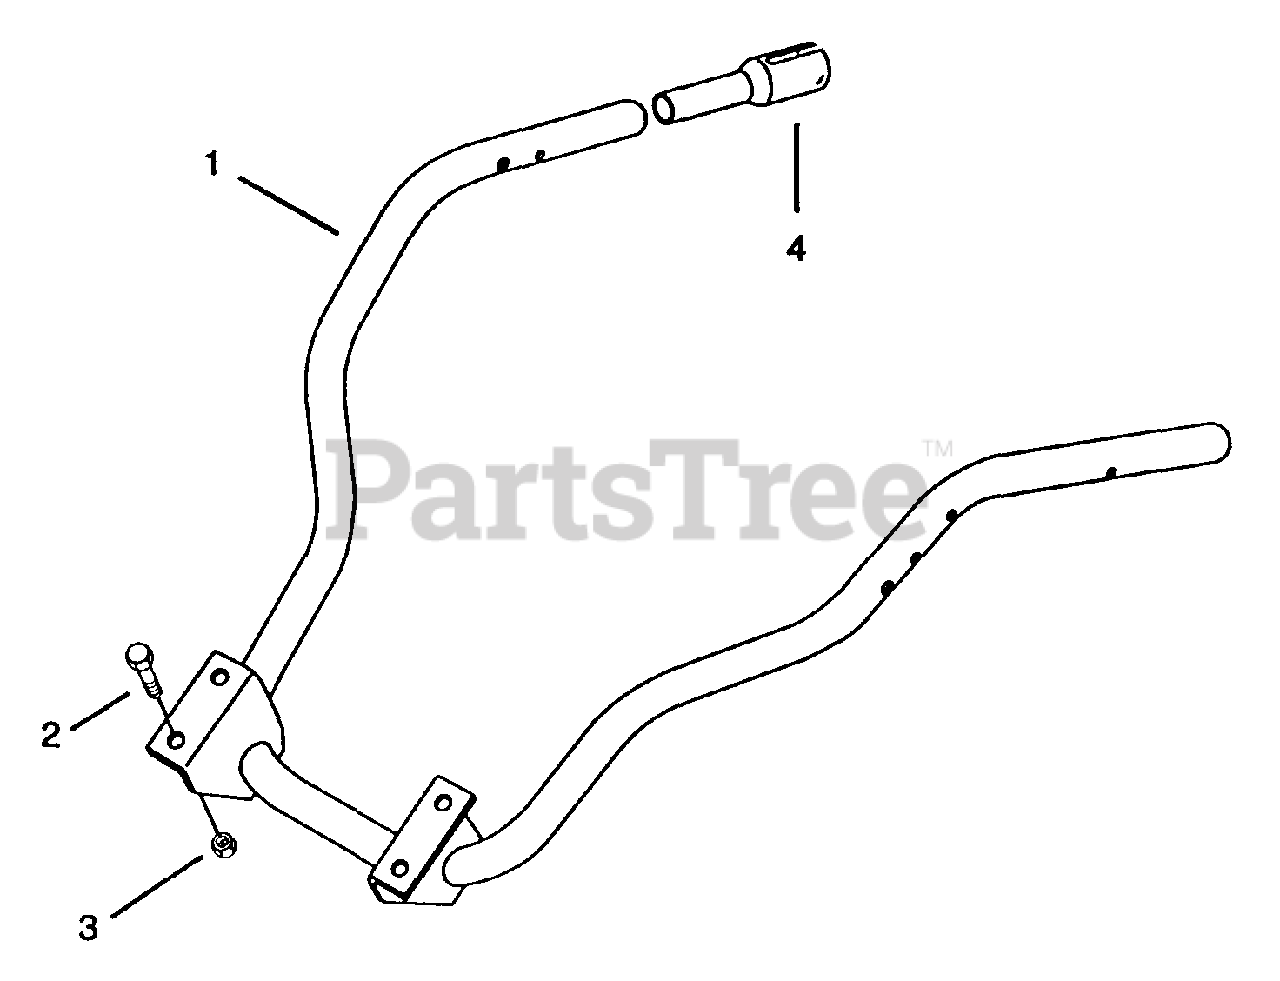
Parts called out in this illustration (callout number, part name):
1	Weldment, Handlebar
2	Bolt-Hex .38-16 x 1.25 Grade 8
3	Nut-Locking-Nylon .375-16 Grade 2
4	Insert, Handlebar
